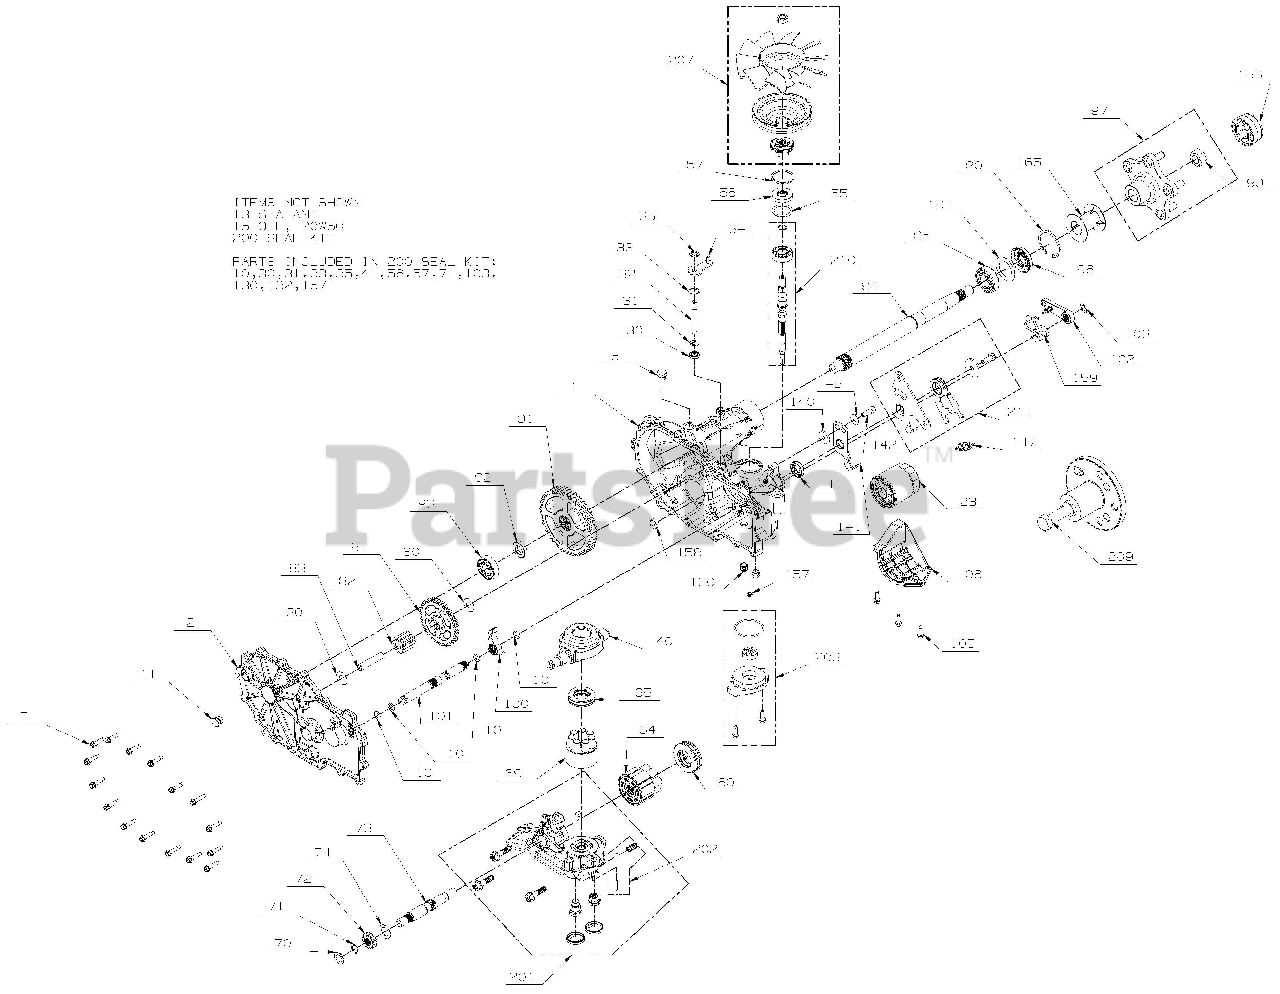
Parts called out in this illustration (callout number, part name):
1	KIT, MAIN HOUSING LH, CHARGE, CONTROL
2	KIT, COVER, SIDE LH
7	SCREW,HEX WASHER 1/4-20X1.125
13	SEALANT TUBE 10.1OZ.
23	OIL FILTER, TRANSMISSION
30	SEAL, LIP .375X.75X.25
31	RING. RETAINING
33	RING, RET .750
34	HG BYPASS ARM (52370)
35	RING, RTNG .
40	TRUNNION, SWASHPLATE
41	SEAL, LIP 18X32X7
45	WASHER
55	WASHER 1.23X1.56X.04
56	SEAL, LIP 17X40X7
57	RING, RET 1.56 INT
60	HG THRUST BEARING (51462)
64	HG 16CC CYLINDER BLOCK (71579)
65	HG THRUST BLOCK (53502)
69	HG SEVEN PISTON BLOCK (71971)
70	WASHER .63X1.0X.05
71	RING, RET 62 EXT
73	SHAFT, MOTOR
74	WASHER .71 X 1.16 X .04
80	WASHER .5X1.0X.032
82	GEAR, 11T (STEEL)
83	JACK SHAFT (PIN)
90	RING, RETAINING
93	KIT, BEARING
94	SHAFT, AXLE
95	BEARING, BALL 25.4 X 52 X 15
96	SEAL, LIP
97	HUB, HYDROGEAR P/N 71691
99	NUT, HEX, LOCK 3/4-16
100	PAWL, BRAKE
101	SHAFT, BRAKE
102	HG ACTUATING KIT HANDLE
105	HFHCS 1/4-20X.75
106	HG FILTER GUARD LH (52247)
140	SPACER
141	ARM, NEUTRAL LEFT
142	SHCS 5/16-24X1 PATCH
147	RTN SPRING HG 51605
156	CAP, AXLE
158	MAGNET, RING
159	SPRING, TORSION
164	WASHER, 1.355 x 2.035 x .021 FLAT
200	HG SEAL KIT (71976)
201	KIT, CENTERSECTION, LH, CHARGE
202	KIT, CHARGE RELIEF
203	KIT, CHARGE PUMP
207	KIT, FAN/PULLEY
209	HUB PULLER 4 BLT HYDGEAR 71459
210	INPUT SHAFT HG 71978
211	TRN KIT HRDROGEAR P/N 71599
